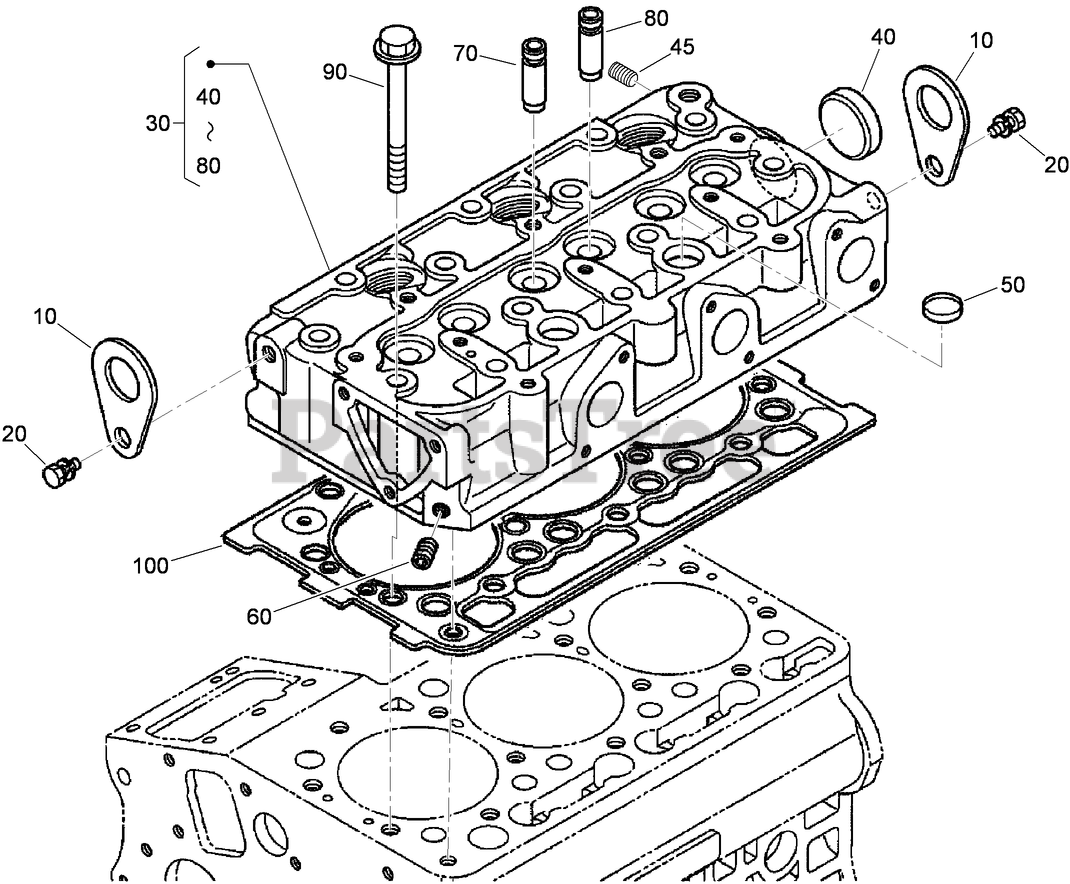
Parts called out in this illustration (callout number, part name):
10	HOOK-ENGINE
30	HEAD-CYLINDER
40	CAP-SEALING
50	CAP-SEALING
60	PLUG
70	GUIDE-VALVE, INLET
80	GUIDE-VALVE, EXHAUST
90	BOLT-HEAD, CYLINDER
100	GASKET-HEAD, CYLINDER
